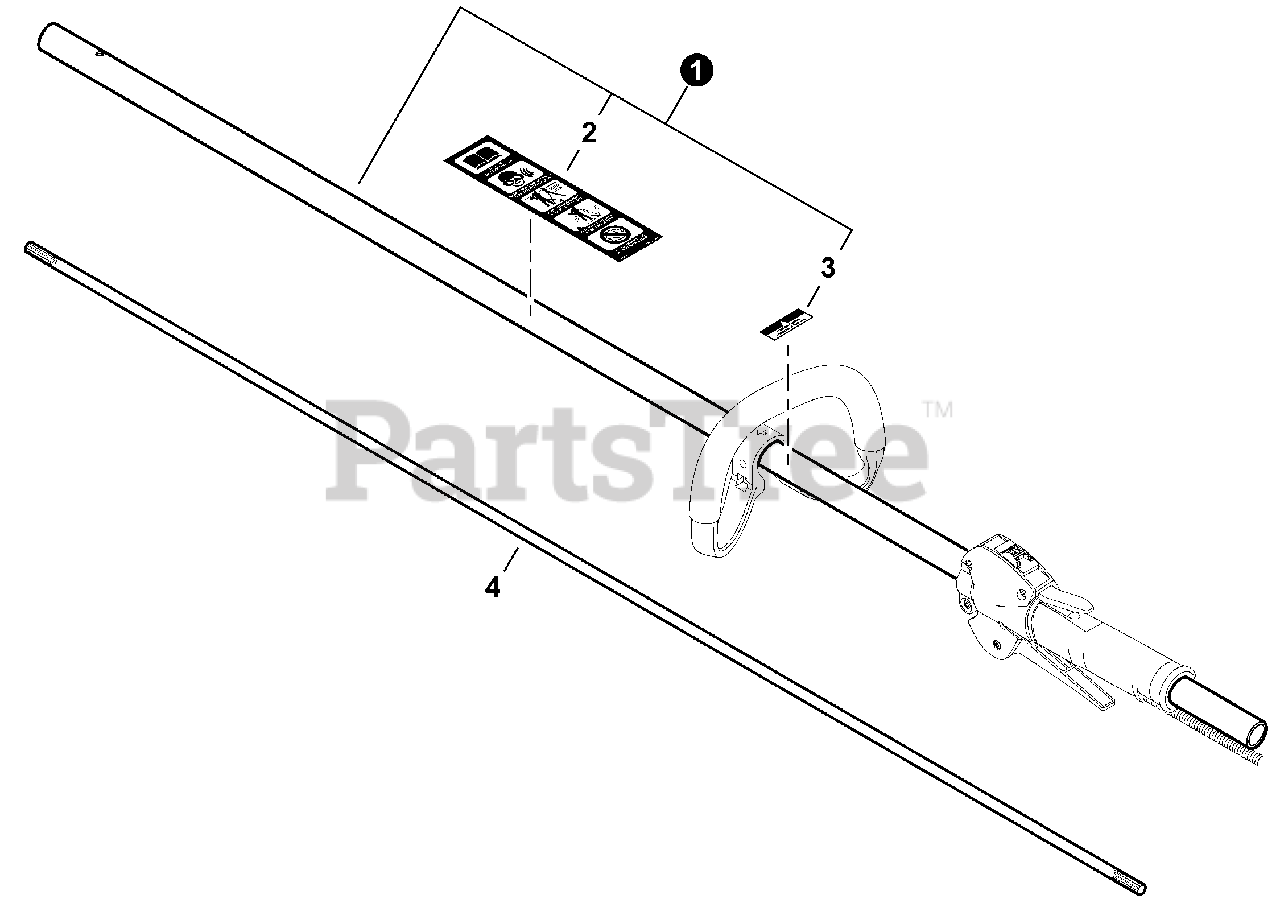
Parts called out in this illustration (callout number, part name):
1	MAIN PIPE ASSY
2	LABEL, CAUTION
3	LABEL, HANDLE
4	MAINSHAFT
